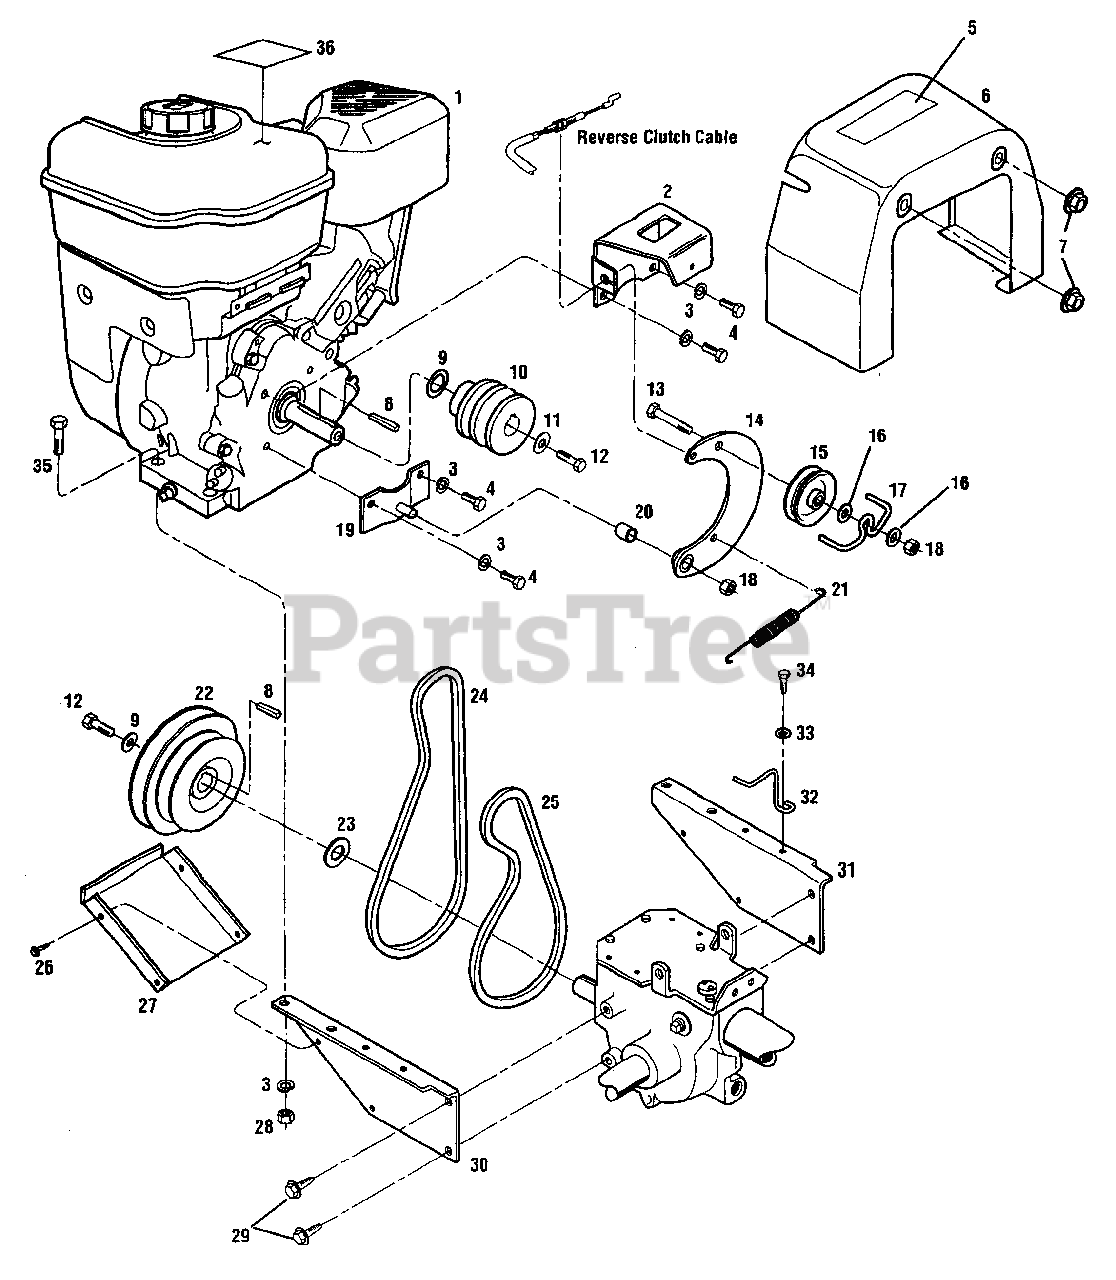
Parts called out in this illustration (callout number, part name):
1	Engine - 7HP, standard recoil start
2	Bracket, Clutch Cable
3	Lockwasher-5/16
4	Hex Hd. Screw, 5/16-24 x 1/2
5	Decal, Hot Surfaces/Belt Warning
6	Cover
7	Flange Lock Nut, 5/16-18
8	Key, 3/16 x 1-1/2
9	Shim
10	Pulley, Engine Drive
11	Belleville Washer
12	Hex Hd. Screw, 5/16-24 x 1-1/8
13	Hex Hd. Screw, 5/16-18 x 2
14	Reverse Idler Arm
15	Pulley, Reverse Idler
16	Flat Washer, 5/16
17	Belt Guide
18	Locknut, 5/16-18
19	Bracket, Reverse Idler
20	Bushing
21	Spring, Reverse Return
22	Transmission Pulley
23	Support Washer
24	Reverse Drive Belt
25	Forward Drive Belt
26	Hex Hd. Screw, #10-32 x 1/2, self-tapping
27	Guard, Belts/Pulleys
28	Hex Nut, 5/16-18
29	Hex Flange Screw, 5/16-18 x 3/4
30	Engine Support Bracket, left side
31	Engine Support Bracket, right side
32	Belt Guide
33	Flat Washer, 1/4
34	Hex Hd. Screw, self-tapping, 1/4-20 x 3/4
35	Hex Hd. Screw, 5/16-18 x 1-1/2
36	Decal, Stabilization
